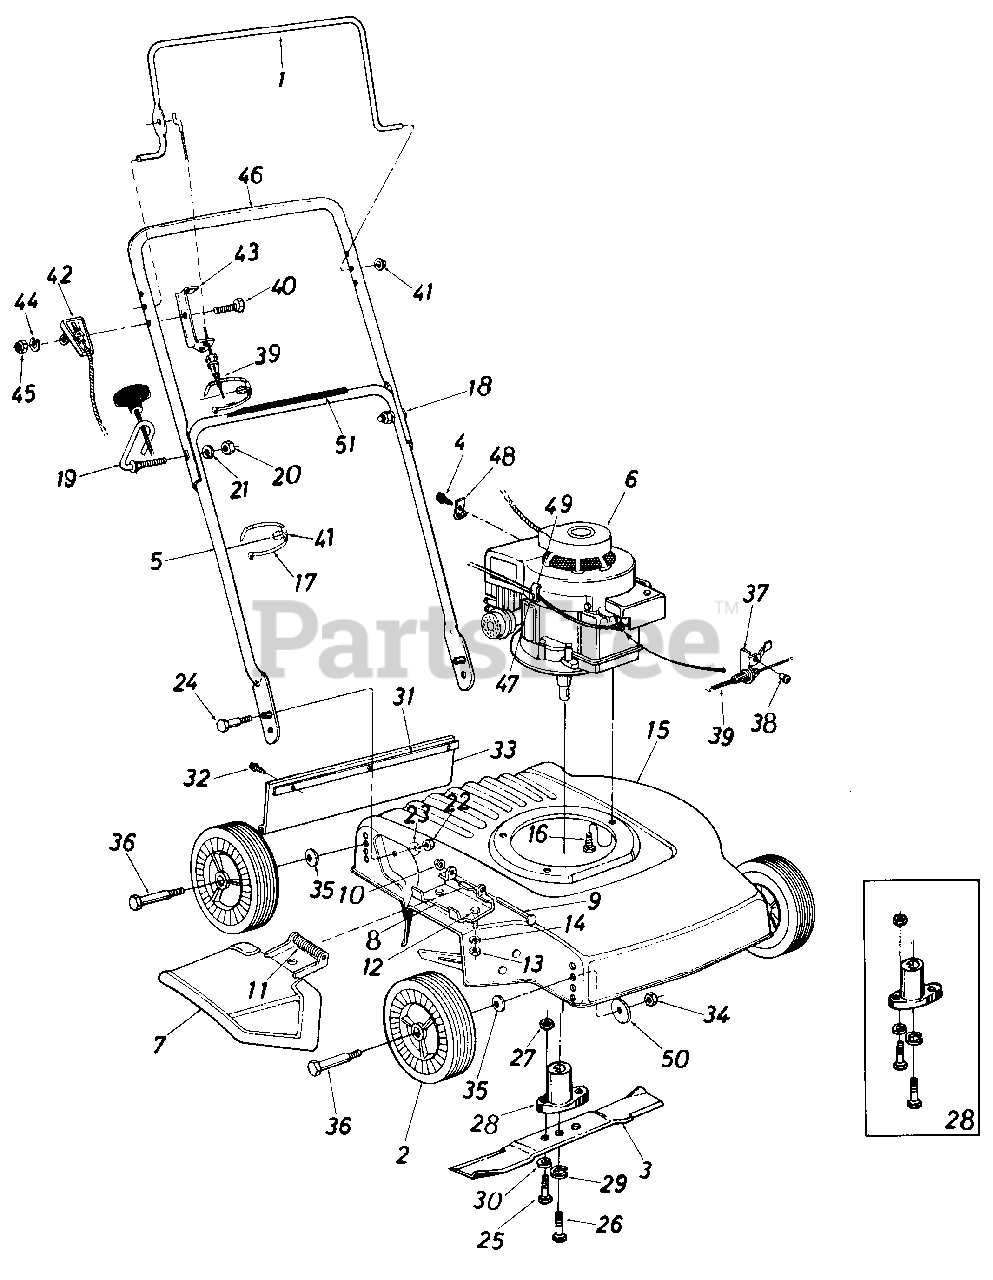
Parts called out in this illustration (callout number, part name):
1	Control Handle-R.H.
3	18" Blade
4	Hex Wash. Hd. AB-Tap Scr. #8 x .50" Lg.
5	Lower Handle (Chrome)
6	Engine
7	Chute Deflector Ass'y.-Comp.
8	Adapter Plate
9	Pivot Pin
10	Push Nut 1/4" Rod
11	Torsion Spring
12	Hex Bolt 1/4-20 x .50" Lg.*
13	Hex Nut 1/4-20 Thd.
14	L-Wash. 1/4" I.D.
15	18" Deck Ass'y.
16	Hex Wash. Hd. TT-Tap Scr. 3/8-16 x 1.00" Lg.
17	Cable Tie
18	Curved Carriage Bolt 5/16-18 x 1.38" Lg.
19	Rope Guide Bolt
20	Hex Nut 5/16-18 Thd.
21	L-Wash. 5/16" I.D.
22	Hex Ins. L-Nut 5/16-18 Thd.
23	Bell-Wash. .345" I.D. x .88" O.D.
24	Shoulder Bolt .437" Dia. x. 180
25	Hex Bolt 5/16-24 x 1.00" Lg.(Grade 5)
26	Hex Bolt 3/8-24 x 2.25" Lg. (Grade 5)
27	Hex Nut 5/16-24 Thd.
28	Blade Adapter Kit
29	L-Wash. 3/8" I.D.-H.D.
30	L-Wash. 5/16" I.D.*
31	Retaining Strip
32	Hex Wash. Hd. AB-Tap Scr. 1/4" x.62" Lg.
33	Rear Flap Ass'y.
34	Hex Nut 3/8-16 Thd.
35	Bell-Wash. .400" I.D. x .88" O.D.
36	Shld Bolt .498" Dia. x 1.450" Lg.
37	Cable Bracket
38	Pop Rivet .156" Dia. x .379
39	Control Cable-43"
40	Hex Bolt 1/4-28 x 1.75" Lg.
41	Cable Anchor
42	Throttle Control Ass'y. Comp.
43	Cable Mounting Brkt.
44	L-Wash. 1/4" I.D.
45	Hex Nut 1/4-28 Thd.
46	Upper Handle (Chrome)
47	Hex B-Tap Scr. #10 x .38" Lg.
48	Casing Clamp
49	Casing Clamp
50	Fl-Wash. .398" I.D. x 1.13"
51	Instruction Label-Handle
